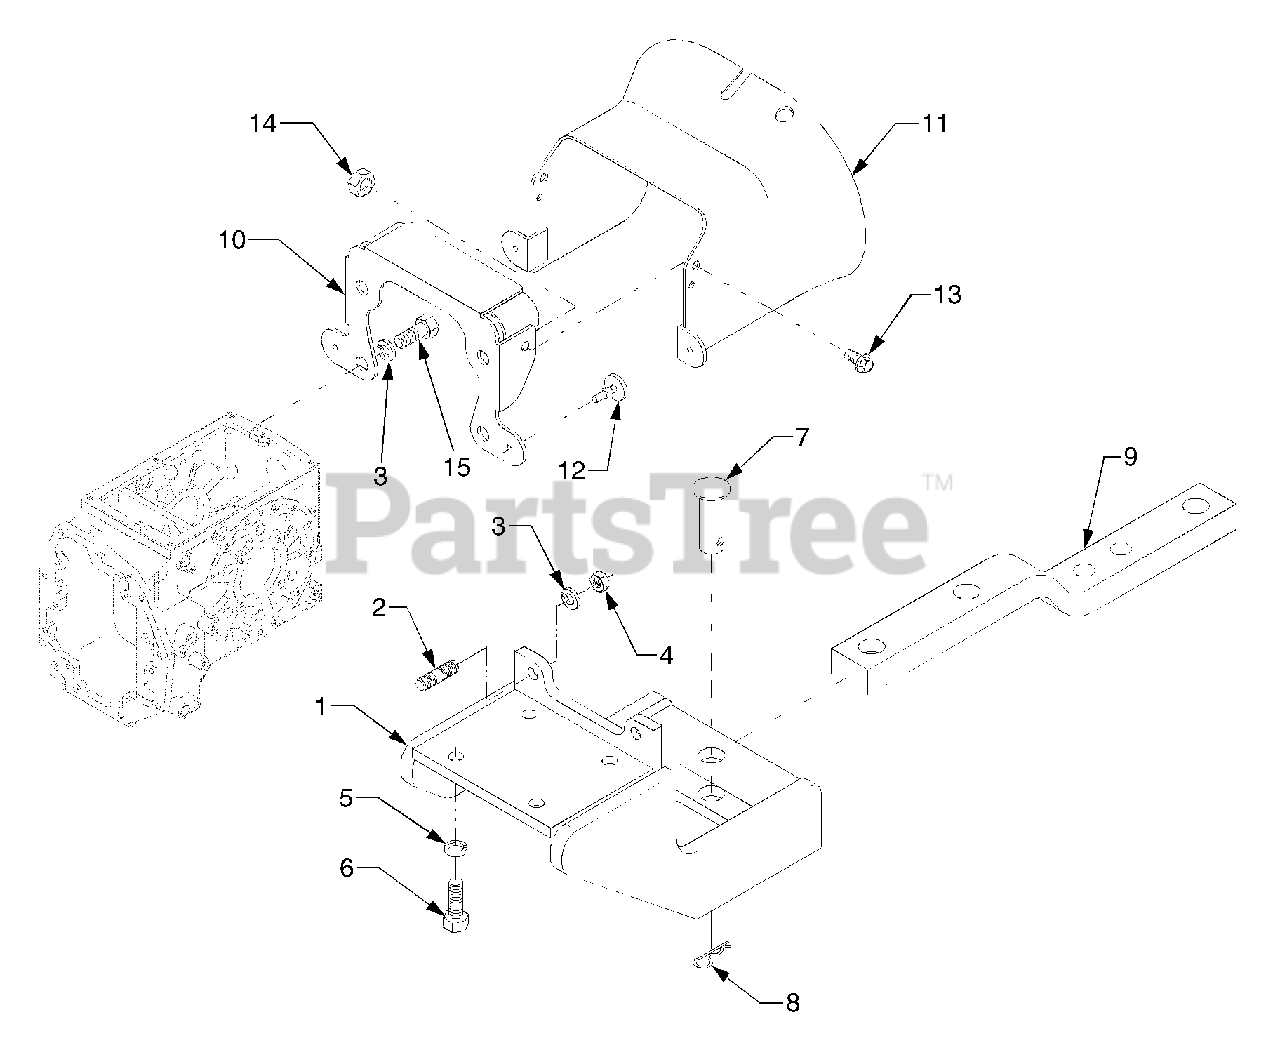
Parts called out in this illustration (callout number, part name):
1	Frame, Swing Drawbar
3	Washer, Spring
5	Spring Washer
9	Drawbar
10	Bracket(Pto Shield)
